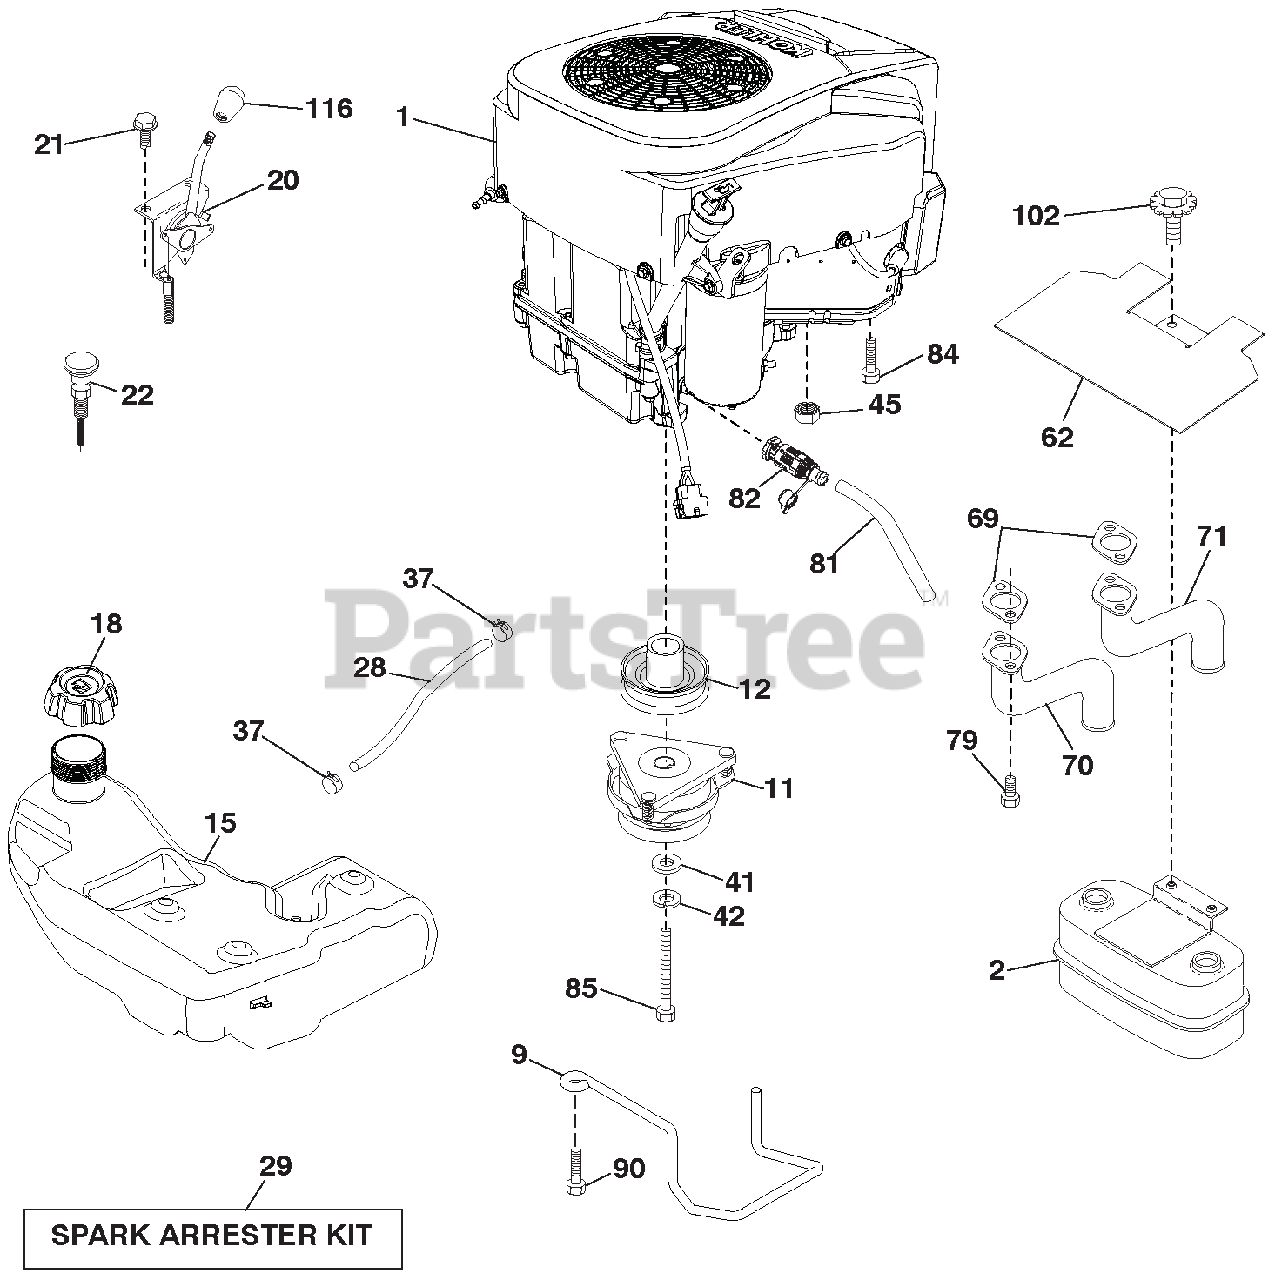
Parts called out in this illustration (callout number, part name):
2	MUFFLER ASM.TWIN.LO-TONE
9	KEEPER.BELT.ENGINE.4.25"
11	CLUTCH ELECTRIC
12	PULLEY.ENGINE
15	TANK.FUEL
18	CAP FUEL
20	CONTROL.THROTTLE
22	CONTROL CHOKE
28	LINE.FUEL.64"REAR.EMIS.CA.LP
29	KIT.SPARK ARRESTOR(392390 B&S)
37	CLAMP.HOSE.BLK.
41	WASHER.1-1/2 ODX15/32 IDX.250
42	WASHER.LOCK.HVY HLCL.SPR.7/16
45	Nut, Keps Hex 1/4-20 unc
62	SHIELD.HEAT.MUFFLER.
70	EXHAUST TUBE LH
71	EXHAUST TUBE RH
79	SCREW.SOCKET HD.5/16-18 X .75
81	TUBE.DRAIN.OIL.EASY
82	VALVE OIL DRAIN
84	SCREW.3/8-16 X 1.SMGML.TAP/R
85	BOLT HEX 7/16-20 X 3.5 GR.5
90	SCREW.3/8-16X1.SMGML.TAP/R.BLK
102	SCREW.5/16-18X3/4.SMGML.TAP/BL
116	KNOB SHIFT
